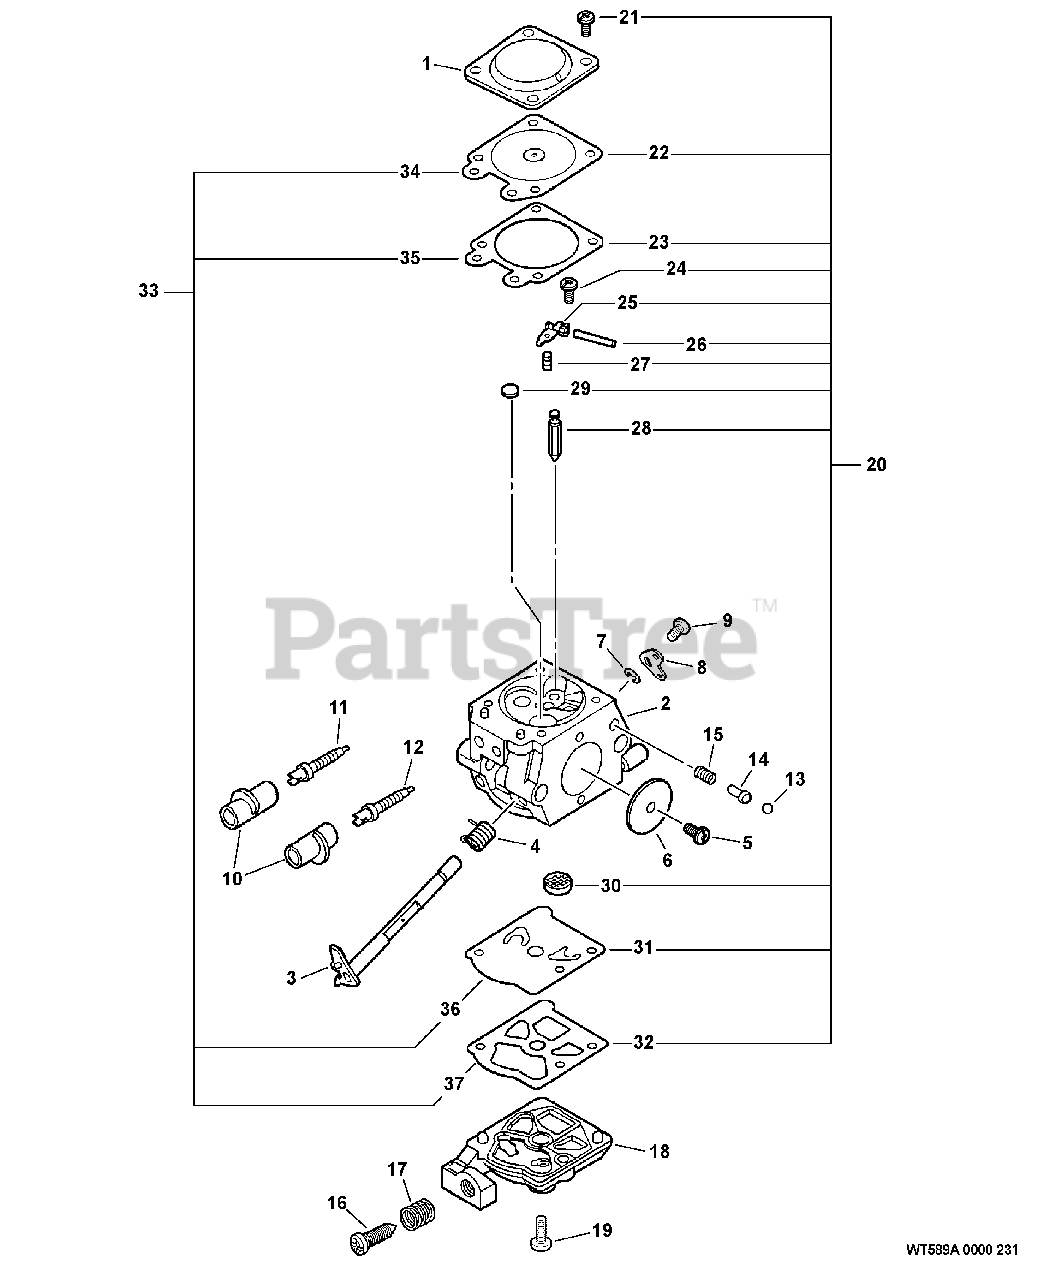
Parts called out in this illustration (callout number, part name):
1	COVER, METERING
2	BODY, CARBURETOR
3	SHAFT, THROTTLE
4	SPRING, THROTTLE RETURN
6	VALVE, THROTTLE
7	RING, RETAINING
8	LEVER, THROTTLE
10	CAP, LIMITER
11	NEEDLE - HIGH SPEED
12	NEEDLE - LOW SPEED
14	PISTON ASSY
16	SCREW, IDLE ADJUST
17	SPRING, IDLE ADJUST
18	COVER, PUMP
19	SCREW, PUMP COVER
20	REPAIR KIT
22	DIAPHRAGM, METERING
23	GASKET, DIAPHRAGM
24	SCREW, METERING LEVER PIN
25	LEVER, METERING
26	PIN, METERING LEVER
27	SPRING, METERING LEVER
28	VALVE, INLET NEEDLE
29	PLUG, WELCH
30	STRAINER
31	DIAPHRAGM, PUMP
32	GASKET, PUMP
33	DIAPHRAGM/GASKET KIT
34	DIAPHRAGM, METERING
35	GASKET, DIAPHRAGM
36	DIAPHRAGM, PUMP
37	GASKET, PUMP
